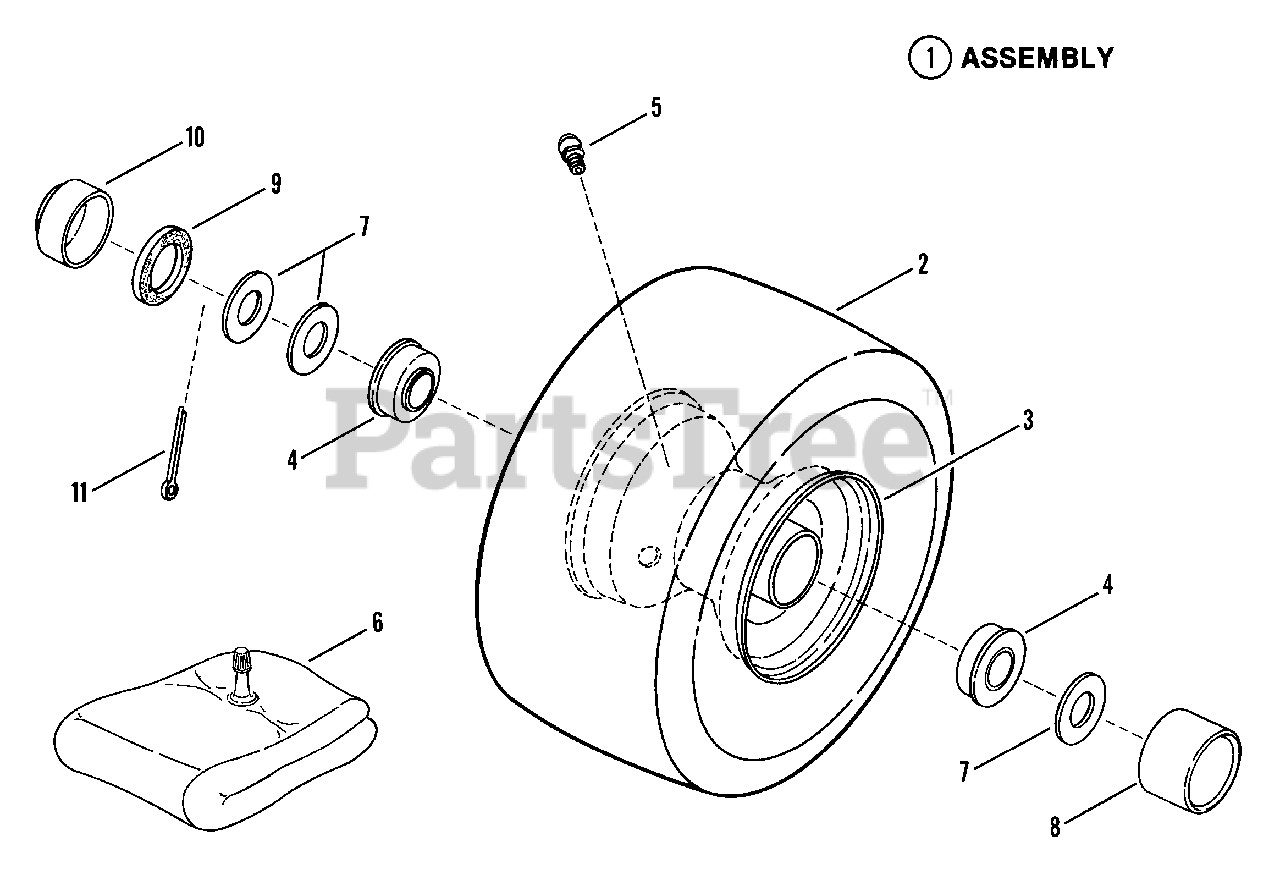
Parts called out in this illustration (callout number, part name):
1	ASSEMBLY, Tire & Rim
2	TIRE, 4.10/3.50x4
3	RIM, (For 4.10/3.50x4 Tire)
4	BEARING, Ball
5	FITTING, Lube
6	TUBE, Inner
7	WASHER,
8	HUB-CAP
9	SEAL, Felt
10	CAP, Dust
11	COTTER-PIN
